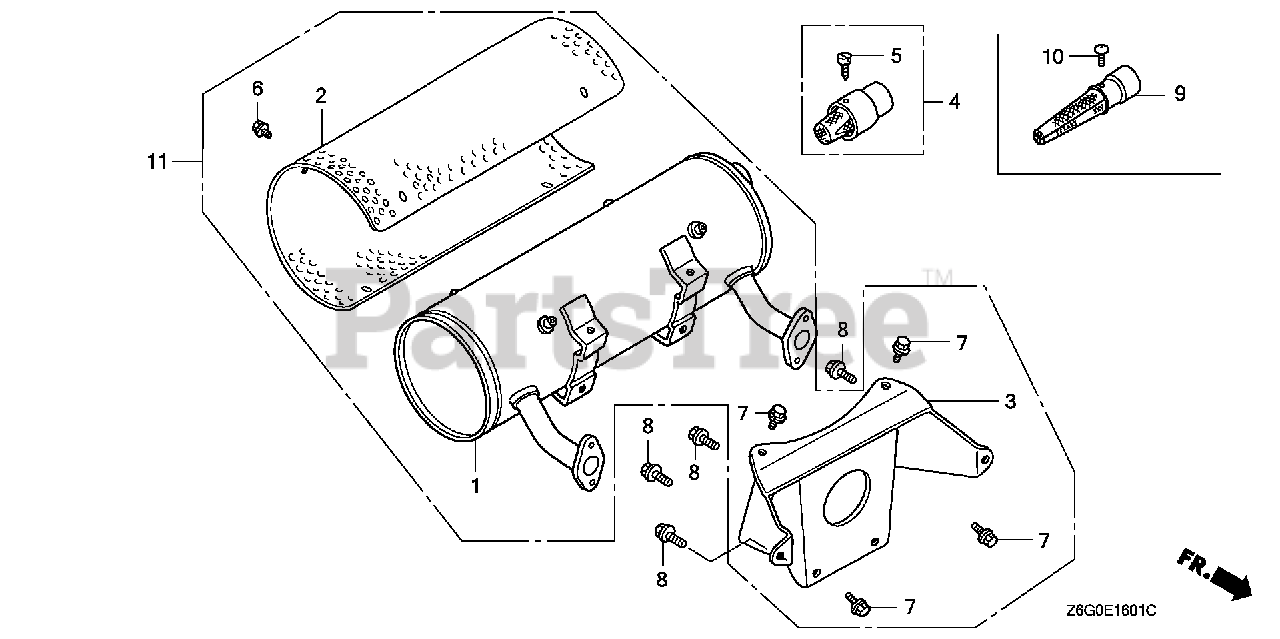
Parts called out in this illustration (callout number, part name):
1	MUFFLER ASSY. (HIGH-L) (FUTABA) (SILVER MUFFLER) (FOR SILVER MUFFLER)
1	MUFFLER COMP. (HIGH-L) (FUTABA) (SILVER MUFFLER) (FOR SILVER MUFFLER)
2	PROTECTOR, MUFFLER (HIGH) (FUTABA) (FOR BLACK MUFFLER)
2	PROTECTOR, MUFFLER (HIGH) (FUTABA) (FOR SILVER MUFFLER)
2	PROTECTOR, MUFFLER (HIGH)(NELSON) (FOR BLACK MUFFLER)
3	STAY, MUFFLER (HIGH-FUTABA) (FOR SILVER MUFFLER)
4	ARRESTER, SPARK (FOR BLACK MUFFLER)
5	SCREW (NELSON) (SCREW UNAVAILABLE SEPARATELY. ORDER DEFLECTOR KIT.)
6	BOLT, FLANGE (6X8)
7	BOLT, FLANGE (8X14)
8	BOLT, FLANGE (8X20) Use up to Engine SN 1609606.
9	ARRESTER KIT (HIGH)
9	ARRESTER, SPARK (FOR SILVER MUFFLER)
10	SCREW, TAPPING (5X8) (FOR SILVER MUFFLER)
11	MUFFLER ASSY. (HIGH-L) (FUTABA) (SILVER MUFFLER) (FOR SILVER MUFFLER)
